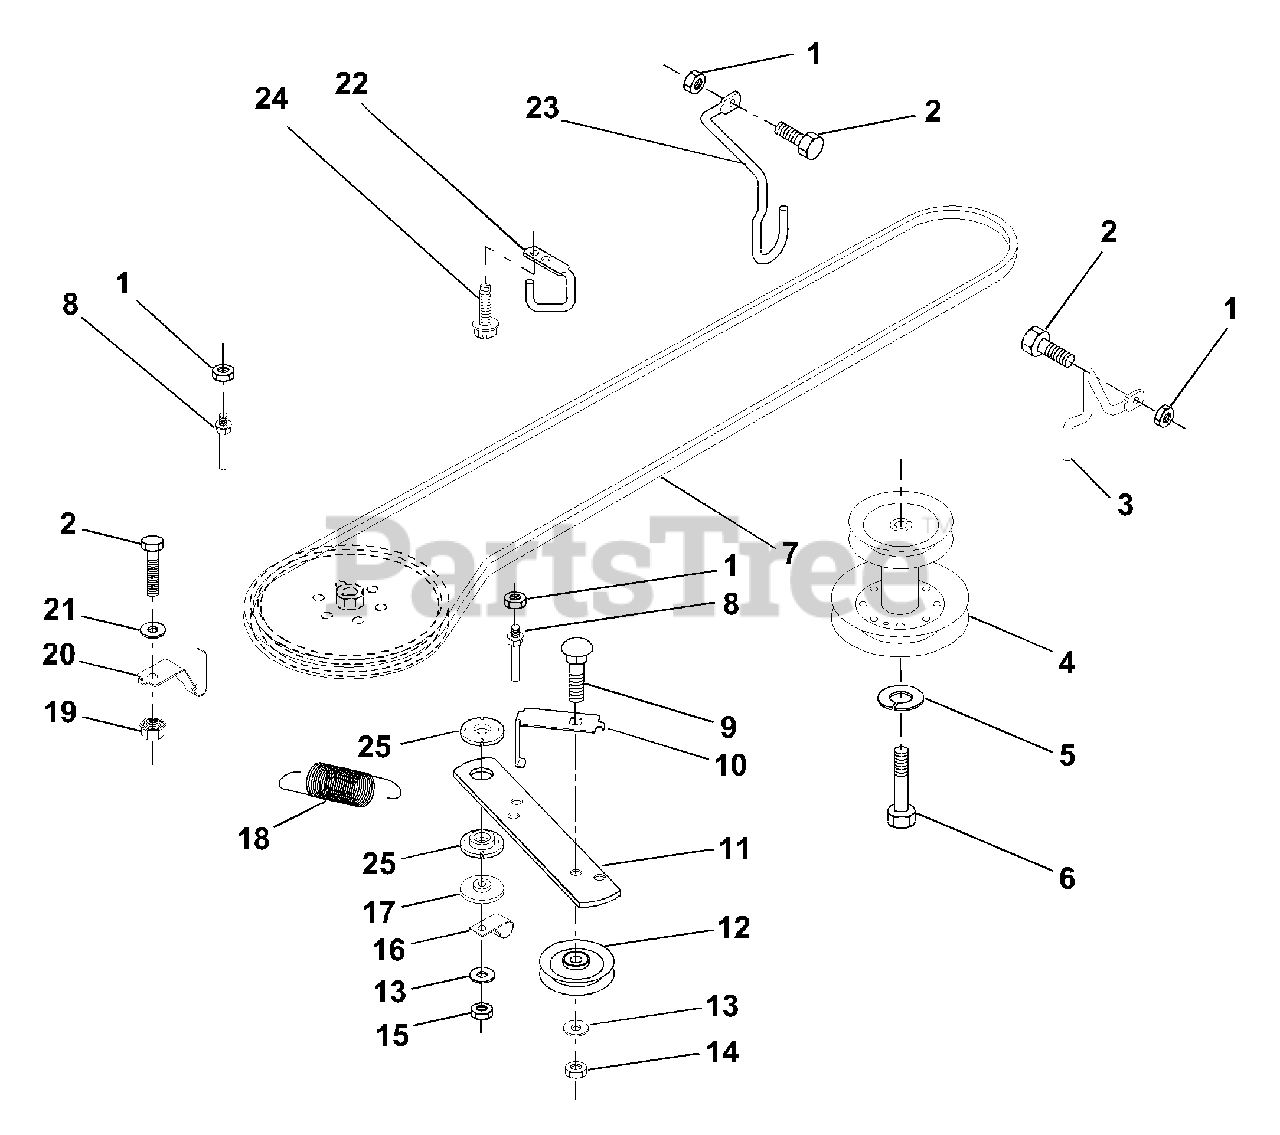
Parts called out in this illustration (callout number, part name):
1	Nut, Crownlock 5/16-18
2	Bolt, Hex Hd 5/16-18 UNC x 3/4
3	Keeper, Mower Drive, R. H.
4	Pulley, Engine
5	Washer, Lock 7/16
6	Bolt Hex 7/16-20 Gr. 5
7	Traction, V-Belt Drive
8	Keeper, T/A Ground Drive Belt
9	Bolt, Carr. 3/8-16 UNC x 1-1/2
10	Keeper, Belt Ground Drive Idler
11	Arm, Ground Drive Clutch
12	Idler, Flat
13	Washer 13/32 x 13/16 x 16 Ga.
14	Nut, Centerlock 3/8-16 UNC
15	Nut, Crownlock 3/8-16 UNC
16	Clip, Insulated
17	Spacer, Retainer
18	Spring Extension
19	Nut, Keps 5/16-18 UNC
20	Keeper, T/A Ground Drive Belt
21	Washer 11/32 x 5/8 x 16 Ga.
22	Keeper, Frame Ground Drive Belt
23	Keeper, Mower Drive, L. H.
24	Screw, Thd. Cut 1/4-20 x 1/2
25	Bushing Nylon Collered
